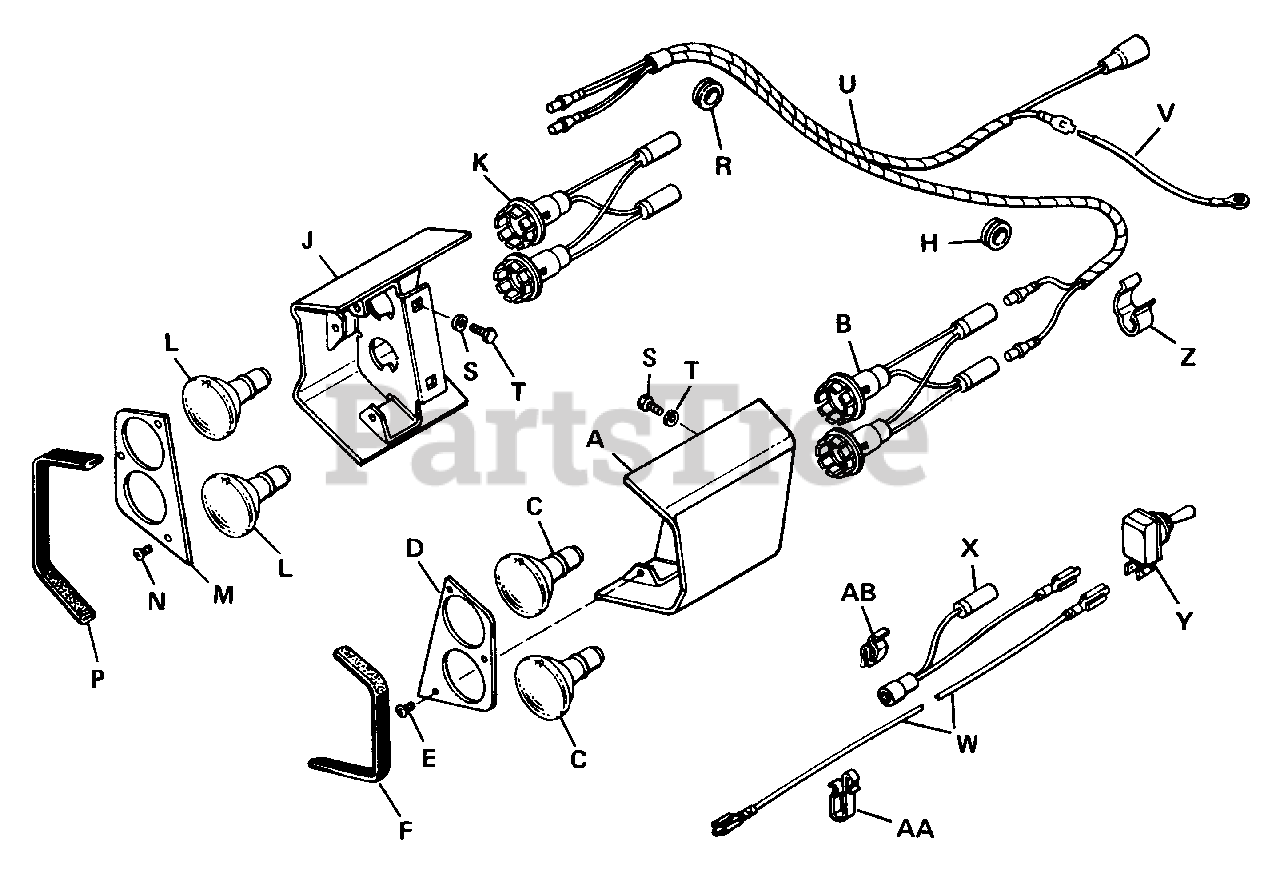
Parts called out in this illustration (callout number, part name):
A	Shroud & Plate Assy. L.H.
B	Lamp Socket & Wire Assy.
C	Headlight
D	Plate, Front
E	Screw, Round Head Phillips Swageform No. 12-24 x 1/2"
J	Shroud & Plate Assy. R.H.
K	Lamp Socket & Wire Assy.
L	Headlight
M	Plate, Front
N	Screw, Round Head, Phillips Swageform No. 12-24 x 1/2"
S	Hex Cap Screw, 1/4"-20 N.C. x 3/4"
T	Lock Washer, 1/4" Std.
U	Harness Assy.
V	Wire Assy., Ground
W	Wire Assy., Light Switch
X	Wire Assy., Indicator Lamp
Y	Switch, Toggle
Z	Cable Clip Tinnerman, Front Frame
AA	Cable Clip Tinnerman, Rear Frame
AB	Cable Clip Tinnerman, Top of Grille
